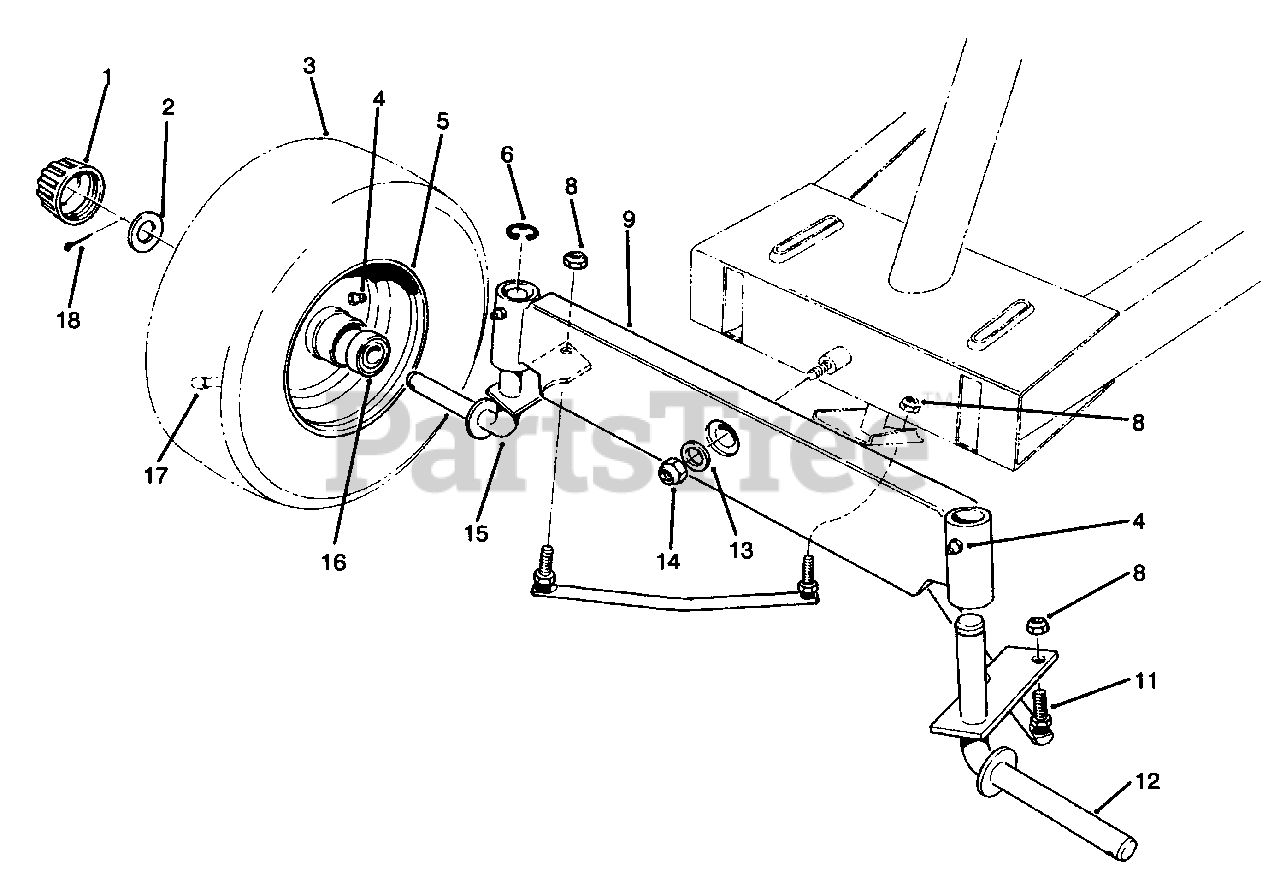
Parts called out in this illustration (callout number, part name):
2	Washer-Flat
4	Fitting-Grease
6	Ring-Retaining
8	Nut-Lock
9	Axle-Front
11	Assembly-Tie Rod
12	Spindle-L.H.
13	Washer-Flat
14	Nut-Lock
15	Spindle-R.H.
16	Bearing
17	Valve Stem w/Cap
18	Pin-Cotter
